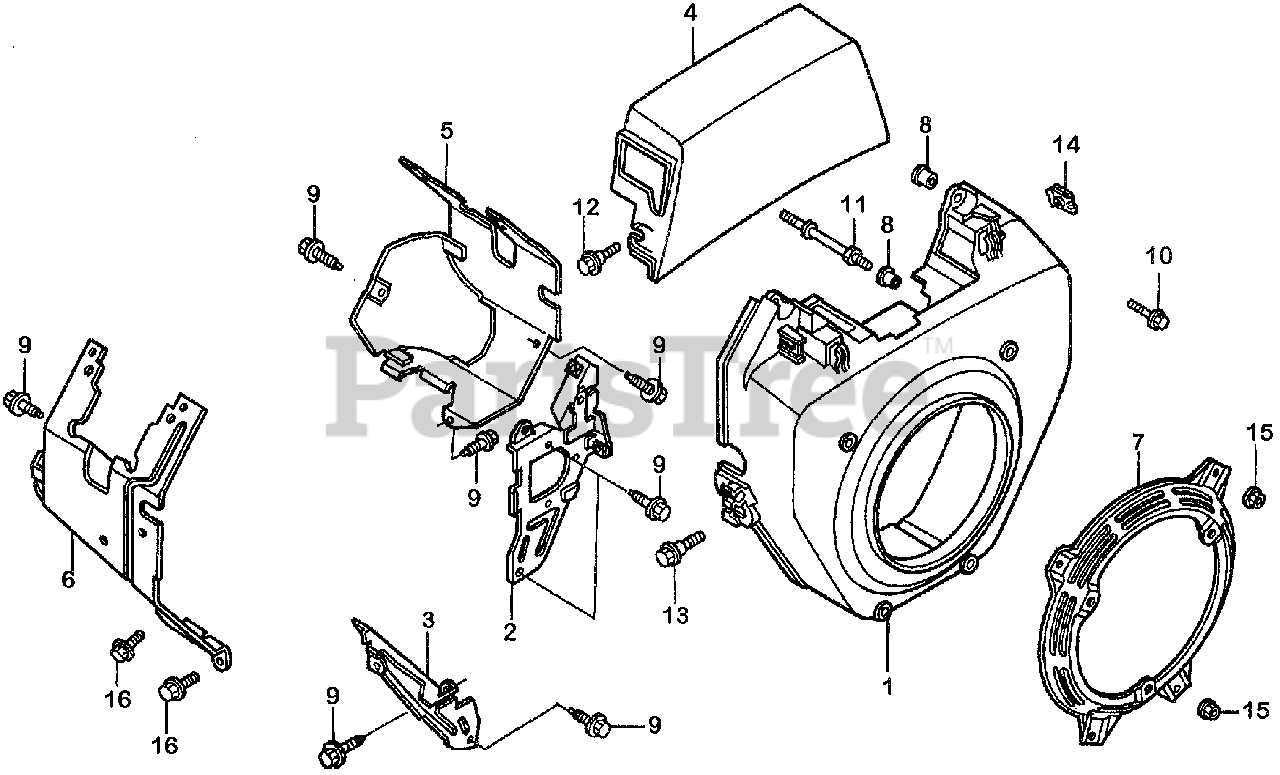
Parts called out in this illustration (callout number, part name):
1	COVER, FAN *R280* (RECOIL STARTER) (POWER RED)
2	PLATE, SIDE (L. SIDE)
3	PLATE, SIDE (R. SIDE)
4	HOOD, FAN COVER
5	SHROUD (R.) (NOT AVAILABLE)
6	SHROUD (R. SIDE)
7	SPACER, RECOIL STARTER MOUNTING *R8* (BRIGHT RED)
8	COLLAR B, TAILLIGHT
9	BOLT, FLANGE (6X12) (CT200)
10	BOLT, FLANGE (6X23)
11	BOLT, STUD (6X73)
12	BOLT, FLANGE (6X20)
13	BOLT, FLANGE (6MM) (BLACK)
14	NUT, SPRING (6MM)
15	NUT, FLANGE (6MM)
16	BOLT, FLANGE (6X8)
